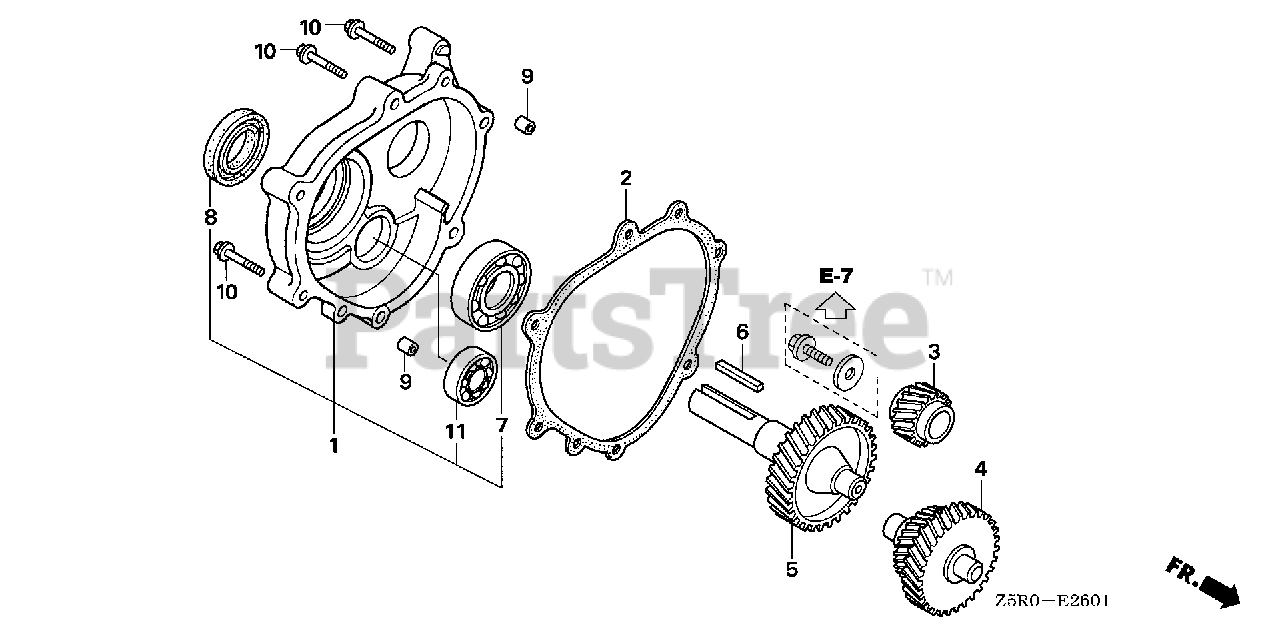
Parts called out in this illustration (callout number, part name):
1	COVER ASSY., GEAR CASE
2	GASKET, CHAIN CASE COVER
3	GEAR, PRIMARY DRIVE (12T)
4	COUNTERSHAFT (13T/27T)
5	SHAFT, P.T.O. (34T)
6	KEY (6.3X6.3X43)
7	BEARING, RADIAL BALL (6206) (NTN)
8	OIL SEAL (30X46X8)
9	PIN, DOWEL (8X14)
10	BOLT, FLANGE (8X40)
11	BEARING, RADIAL BALL (6302)
